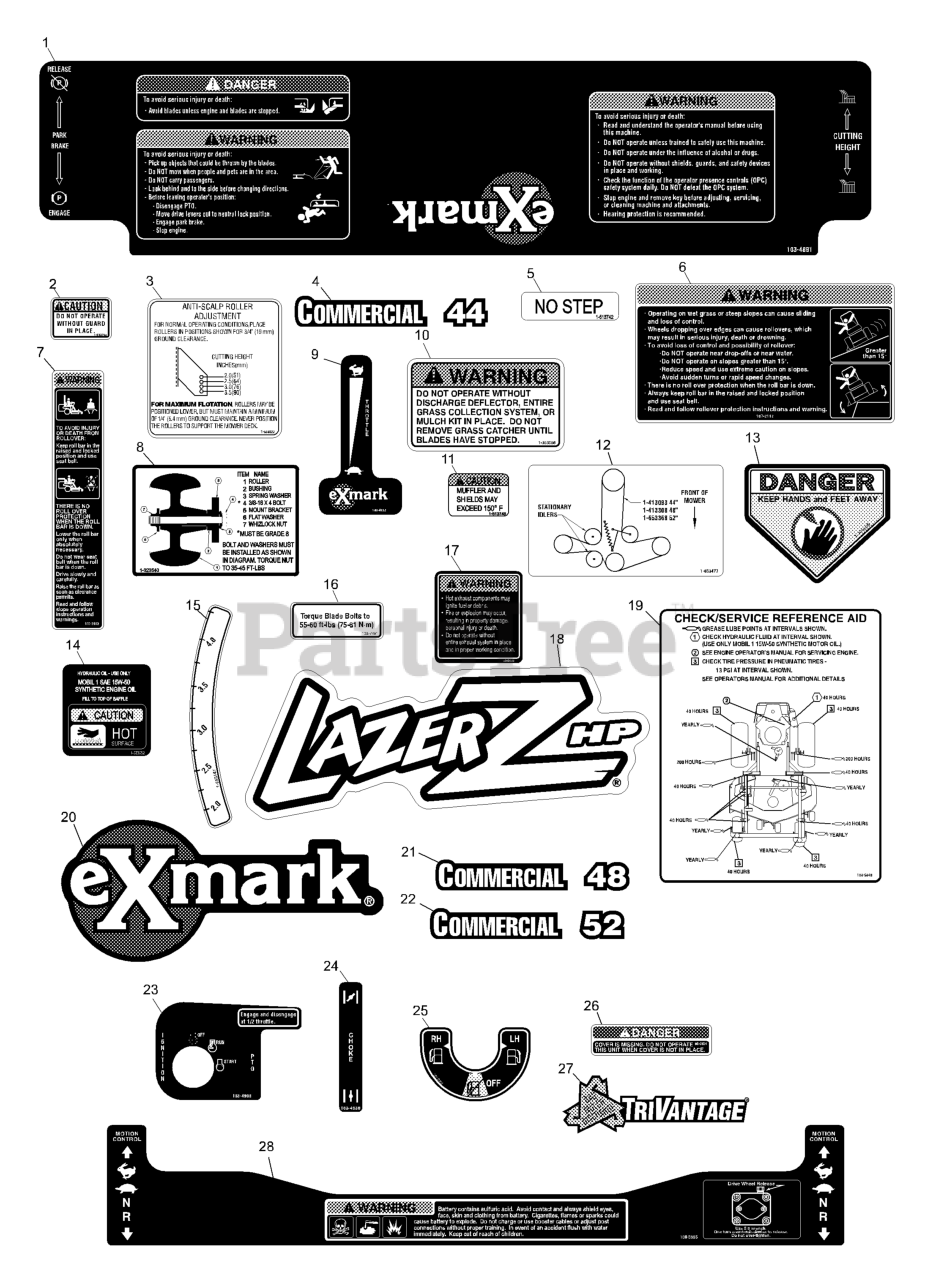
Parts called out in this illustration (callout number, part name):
1	DECAL,CONSOLE LHP
3	DECAL,ANTISCALP
4	DECAL,COMMERCIAL 44
5	DECAL,NO STEP
6	DECAL-WARNING
7	DECAL-WARNING, FOLDING RO
8	DECAL,ROLLER MOUNTING
9	DECAL,THROTTLE
10	DECAL-WARNING, DISCHARGE
11	DECAL-GUARD
13	DECAL-DANGER
15	DECAL-DECK HEIGHT, INNER
17	DECAL-EXHAUST
18	DECAL,LHP MODEL
19	DECAL,CHECK/SERVICE LHP
20	DECAL,EXMARK LOGO
21	DECAL,COMMERCIAL 48
22	DECAL,COMMERCIAL 52
23	DECAL,IGNITION/PTO
24	DECAL,CHOKE
25	DECAL-VALVE, FUEL
26	DECAL-COVER, MISSING
28	KIT,FUEL TANK LH LCT
